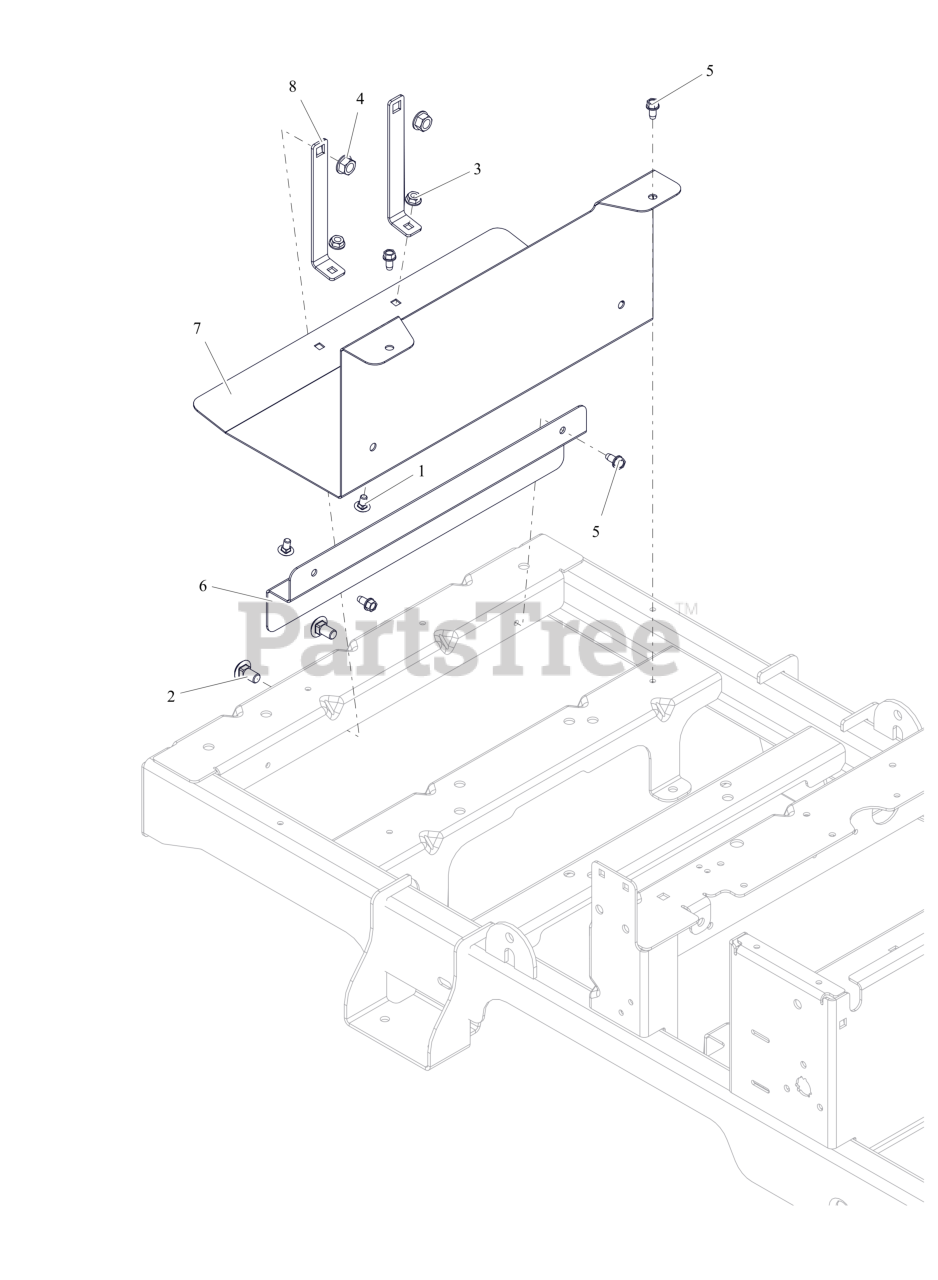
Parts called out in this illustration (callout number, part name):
1	BLT, RHSN .25-20X.500 G5 ZCC
2	BLT, RHSN .38-16X.750 G5 ZCC
3	NUT-LK-CTR-FLG .25-20 ZC120
4	NUT-LK-CTR-FLG .375-16 GF ZCC
5	SCR-TAP .25-20X.50 HWH ZCC
6	GUARD, EXHAUST EDGE CE (BLACK)
7	SHIELD, MUFFLER ZT EDGE CE (BLACK)
8	STRAP, MUFFLER EDGE CE
